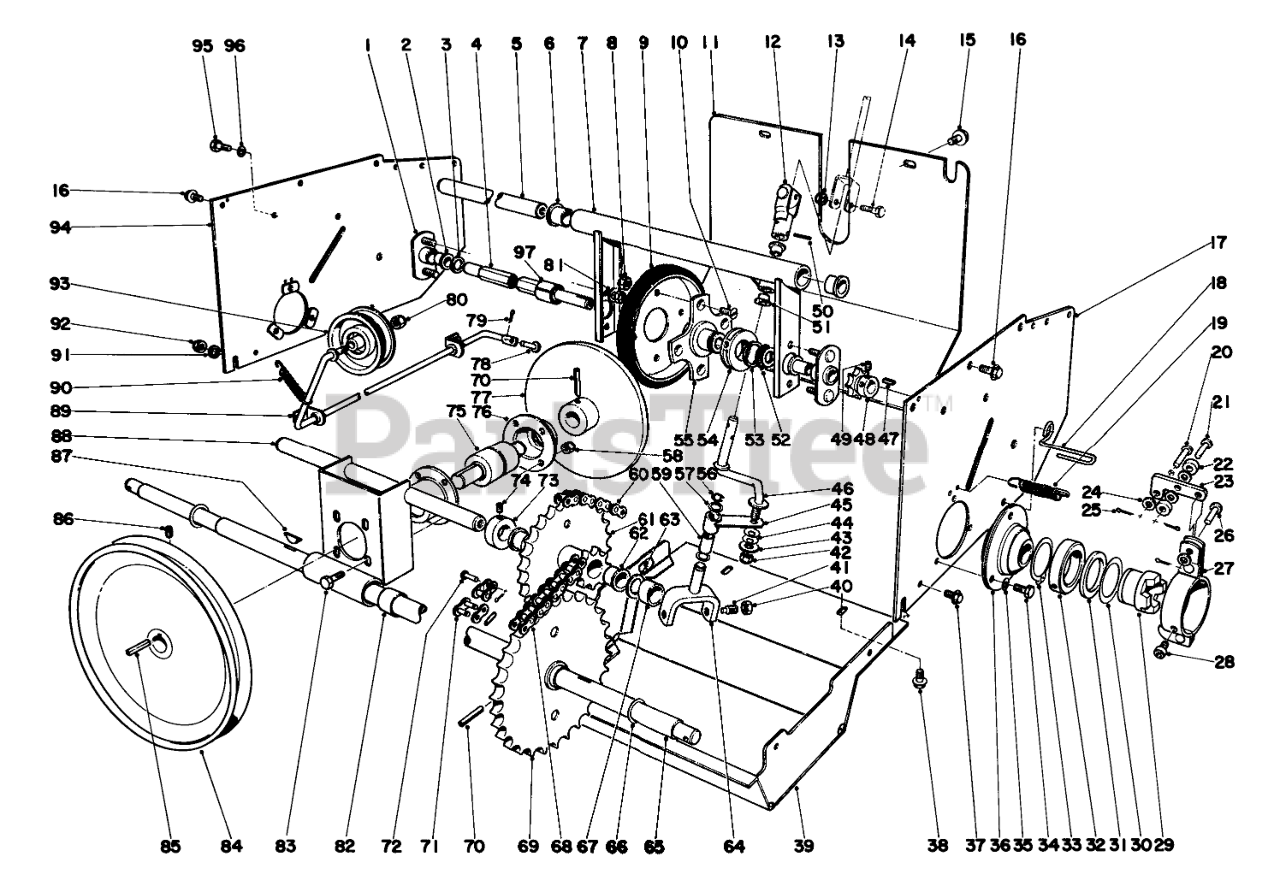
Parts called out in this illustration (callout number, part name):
1	Adjusting Plate (Incl. Ref. No. 2)
2	Bushing
3	WASHER-FLAT
4	Shaft, Friction Wheel
5	Dead Shaft
6	3/4IDX1LG FLANGE BSHG
7	Pivot Tube (Incl. Ref. Nos.6 & 52)
8	Nut
9	Disc
11	Rear Shield
12	U Joint
13	NUT-LOCK
14	SCREW-HH
15	1/4-20 X 1/2 SEMS MS
16	SCREW-HHF
17	Side Plate, Drive
18	Clutch Retainer
19	EXTENSION SPRING
20	PIN-CLEVIS
21	PIN-CLEVIS
22	CLUTCH ROLLER
23	Arm Clutch
24	WASHER-FLAT
25	PIN-COTTER
26	PIN-CLEVIS
27	Clutch Mount Bracket
28	SCREW-HSH
29	Clutch Wheel
30	THRUST WASHER
31	THRUST BEARING
32	CLUTCH MOUNT COLLAR
33	RING-RETAINING, EXTERNAL
34	SCREW-HH
35	WASHER-LOCK
36	Bearing Flange
37	SCREW-HHF
38	Machine Screw
39	Lower Shield
40	NUT-JAM
41	Set Screw
42	NUT-LOCK
43	WASHER-FLAT
44	WASHER-SPRING
45	Shift Rod (Incl. Ref. No. 60)
46	Connecting Rod
48	SPROCKET
49	Set Screw
50	PIN-SPRING
51	BUSHING-FLANGE
52	RING-RETAINING
53	WASHER-THRUST
54	Ring Slider
55	Hub Traction
56	E-RING
57	Thrust Washer
58	Nut
59	Bushing
60	1/4 X 42 CHAIN W/LINK
61	Sprocket & Hub (Incl. Ref. No. 63)
62	3/4ID X 3/4LG BSHG
63	WASHER-THRUST
65	Axle Shaft
66	WASHER
67	Spacer Idler
68	Chain Lower
69	Sprocket
70	PIN-SPIRAL
71	LINK-CONNECTING
72	1/4 OFFSET LINK
73	Collar
74	SCREW-HSH
75	Friction Plate Shaft
76	HOUSING BEARING
77	Friction Plate
78	PIN-CLEVIS
79	PIN-COTTER
81	WASHER-PLAIN
82	Bushing
83	SCREW-HH
84	Pulley
85	KEY-SQUARE
86	SCREW-SET,
88	Bulkhead (Incl. Ref. No.82)
89	Auger Clutch Rod
90	EXTENSION SPRING
91	WASHER-FLAT
92	NUT-HEX
93	PULLEY-IDLER
94	Side Plate Drive
95	SCREW-HH
96	WASHER-LOCK
97	SPLIT SPACER
